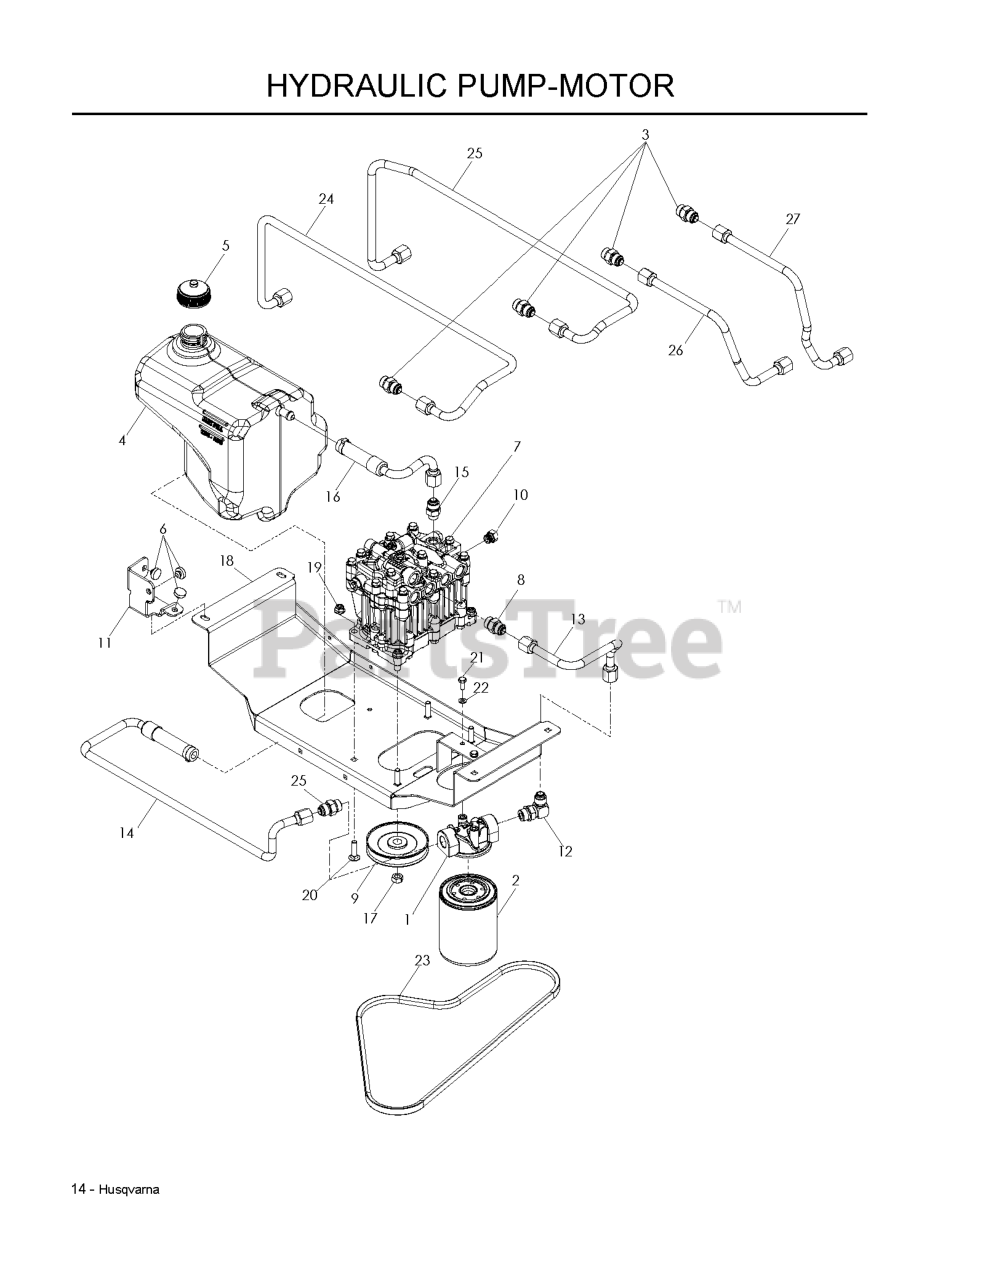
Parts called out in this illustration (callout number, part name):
1	FILTER HEAD
2	HYDRAULIC OIL FILTER
3	FITTING, STRAIGHT F6400-8-8-0
4	RESERVOIR HYDRO
5	HYDRAULIC CAP
6	GROMMET, BUMPER
7	PUMP, DUP10S (77808041201)
8	FITTING, 10-8 STRAIGHT
9	PULLEY, PUMP
10	PLUG, 6408-6
11	SUPPORT, RESERVOIR
12	FITTING, 10-8 90 DEG
13	HYD LINE, CHARGE
14	HYD LINE, INLET
15	FITTING, HYDRO
16	HYDRO LINE, CASE
17	NUT M10-1.5 L/H HEX
18	PLATE, PUMP
19	5/16-18 NYLOC FLANGE NUT
20	BOLT, CARRIAGE 5/16X1-1/4
21	HCS 1/4C X 5/8
22	LOCKWASHER 1/4"
24	HYDRO LINE, 72A
24	HYDRO LINE, 72C
24	HYDRO LINE, 72D
24	HYRO LINE, 72B
